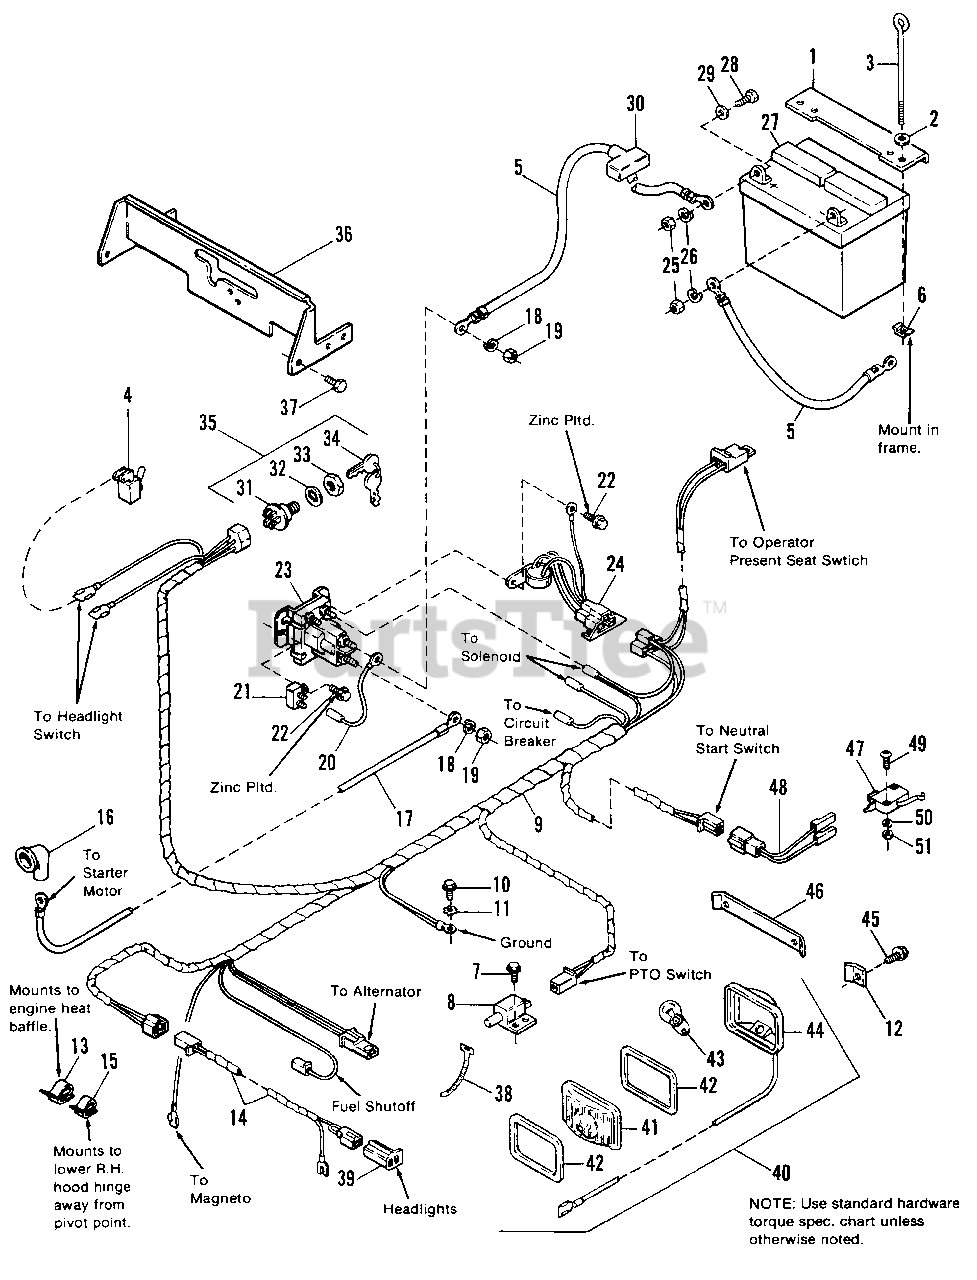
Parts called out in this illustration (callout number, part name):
1	HOLD DOWN, Battery
2	WASHER, 1/4
3	ROD, Battery Hold Down
4	SWITCH, Headlight
5	CABLE, Ground
6	NUT, Retainer, 1/4-20
7	SCREW, Taptite, #10-24 x 1/2
8	SWITCH, PTO
9	HARNESS, Wiring
10	SCREW, Taptite, 1/4-20 x 3/8
11	WASHER, Ext. Tooth
12	CLIP, Side, Headlight
13	CLIP, Wire
14	WIRE ASSY., Headlights
16	COVER, Terminal
18	LOCKWASHER, 5/16
19	NUT, Hex, 5/16-24
21	CIRCUIT BREAKER
22	SCREW, Taptite, 1/4-20 x 5/8, Zinc Pltd.
23	SOLENOID
24	MODULE, DSI Interlock, Seat Switch
25	NUT, Hex, 1/4-20
26	LOCKWASHER, 1/4
27	BATTERY, 39 Amp.
28	CAPSCREW, Hex Hd., 1/4-20 x 3/4
29	WASHER, 1/4 I.D.
30	BOOT, Insulator
32	LOCKWASHER, Internal, 5/8
33	NUT, Hex, 5/8-32
35	SWITCH, Ignition (Incl. Ref. Nos. 31, 32, 33 & 34)
36	QUADRANT, Shift
37	SCREW, Taptite, 1/4-20 x 3/8
39	CONNECTOR
40	LIGHT ASSY.
41	LENS, Plastic, Clear
44	REFLECTOR ASSY.
45	SCREW, Platite, #10-14 x 1/2
46	CLIP, Center, Headlight
47	SWITCH, Transmission Interlock
48	ADAPTOR, Wire
49	SCREW, Phillips #5-40 x 3/4
50	LOCKWASHER, #5
51	NUT, Hex, #5-40
